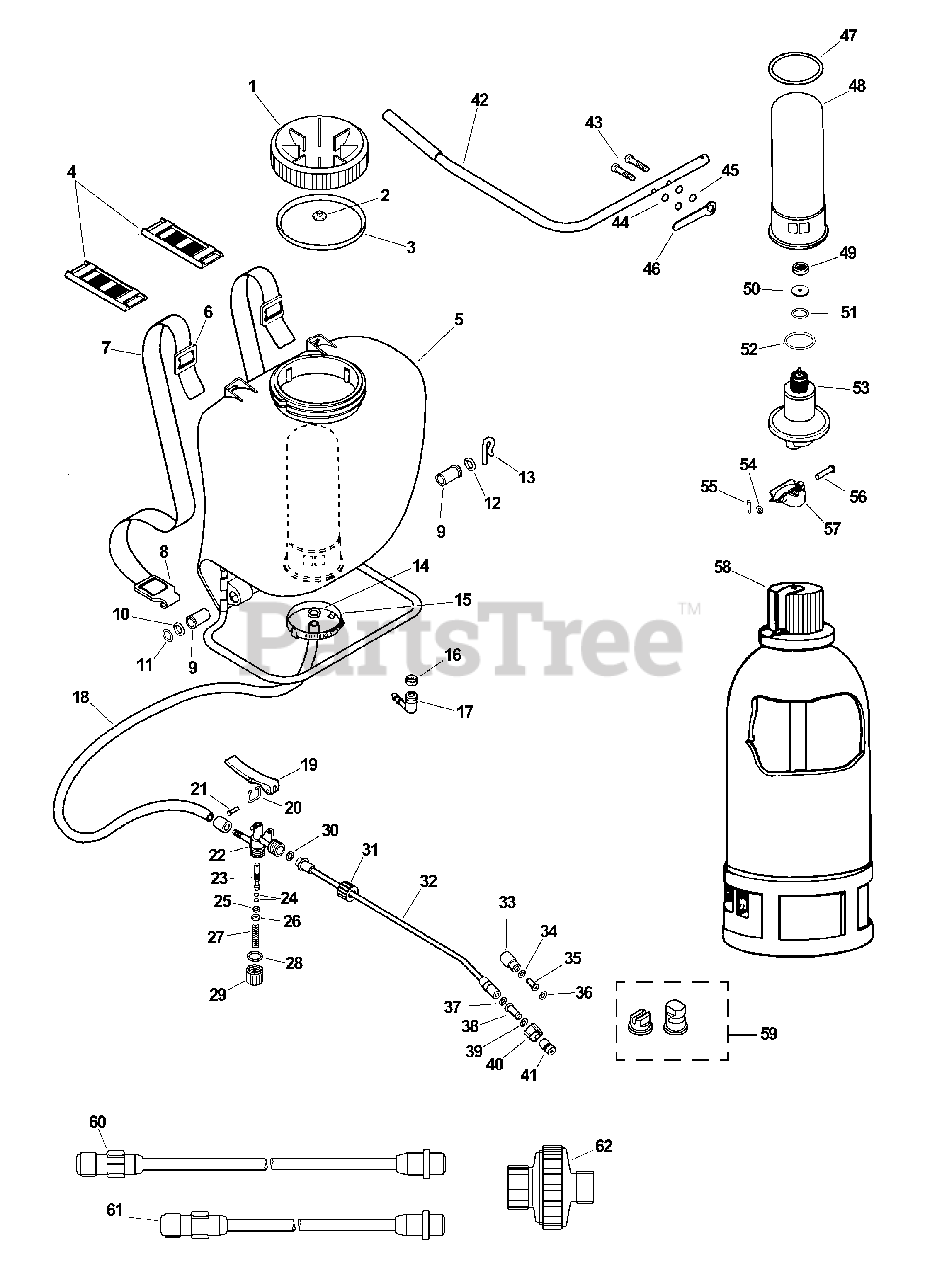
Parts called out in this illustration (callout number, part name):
1	CAP ASSY
2	VALVE, CHECK
3	SEAL, CAP
4	PAD, SHOULDER STRAP
6	HOOK
7	STRAP ASSY
8	HOOK, STRAP
9	BEARING - NYLON
10	WASHER - NYLON
11	WASHER
12	WASHER - NYLON
13	PIN, SPLIT
14	CLAMP, HOSE
15	CLAMP
16	HOLDER
17	FITTING - 90°
18	HOSE
18	HOSE, RUBBER
19	HANDLE, PISTON
20	HOLDER
21	PIN, PISTON
22	SPRAY PISTOL ASSY
23	SPINDLE SET
24	O-RING KIT
25	STOPPER
26	WASHER - RUBBER
27	SPRING
28	O-RING
29	PLUG SET
30	O-RING
31	COUPLER
32	WAND - ALUMINUM
32	WAND - BRASS
32	WAND - PLASTIC
33	STRAINER, DEBRIS
34	WASHER
35	CORE
36	SCREEN, SPARK ARRESTOR
37	O-RING
38	JET
39	O-RING
40	NOZZLE HOLDER KIT
41	BRASS NOZZLE ASSY
42	HANDLE ASSY
43	SCREW - SET
44	WASHER
45	NUT
46	WRENCH
47	O-RING
48	TANK, PRESSURE
49	SEAL KIT
50	DISK
51	O-RING
52	O-RING
53	PUMP MODULE
54	WASHER
55	PIN, SPLIT
56	PIN
57	CRANKSHAFT ASSY
58	AGITATOR, REGULATOR
59	SPRAY TIP SET
60	SPRAY WAND, BRASS 66-1/2 INCH
61	SPRAY WAND, BRASS 26-1/2 INCH
62	STRAINER, DEBRIS
